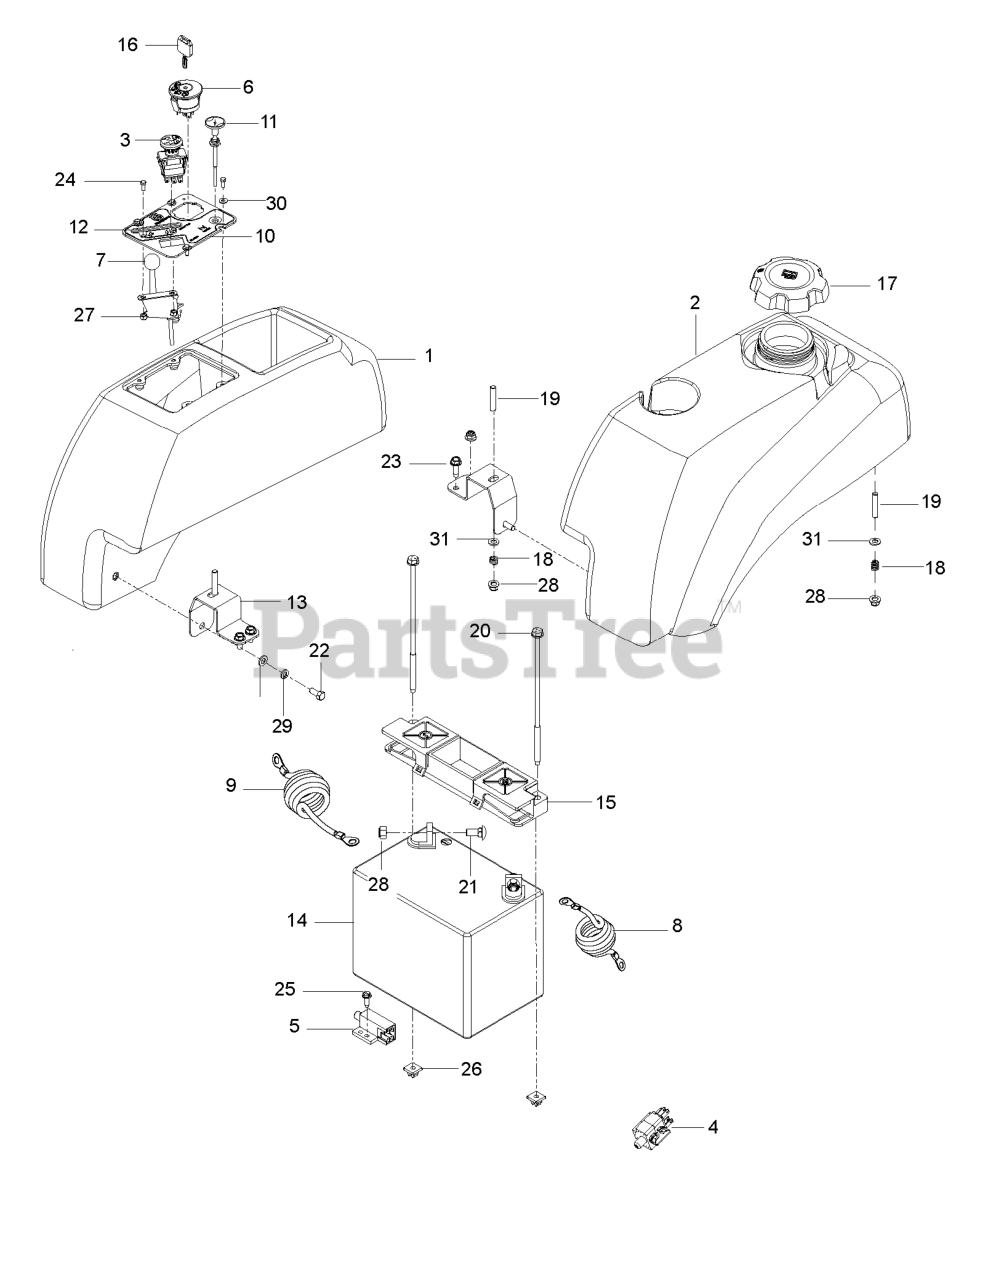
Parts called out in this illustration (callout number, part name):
1	FENDER CONSOLE
2	LEFT TANK W/CUP HOLDER
3	RP SWITCH.PTO.TERMINAL.STD.RED
4	SWITCH, BRAKE 3P
5	SWITCH, INTERLOCK
6	RP IGNITION SWITCH
7	THROTTLE CABLE
8	POSITIVE CABLE, 46"
9	NEG. CABLE, 28"
10	CONSOLE PLATE, BLACK
11	CHOKE CONTROL
12	DECAL, CONSOLE
13	SUPPORT, TANK, BLK
14	BATTERY, 12 V 330 AMP
15	BATTERY HOLD DOWN
16	KEY
17	FUEL CAP, HTC
19	STUD, 5/16C
20	BOLT - 1/4-20 X 7.5
21	BOLT 5/16C X 3/4" CARRIAGE
22	HCS 5/16C X 3/4
23	RP BLT 5/16-18 X 1 THRD FORM D
24	HCS #10-24 X 1/2
25	SCREW #10 X 1/2 SELF TAPPING
26	PUSH NUT-NYLON
27	NUT 10-24 NYLOC
28	5/16-18 NYLOC FLANGE NUT
29	WASHER.LOCK.HVY.HLCL.SPR.5/16
30	WASHER #10
31	FLAT WASHER 5/16 SAE
